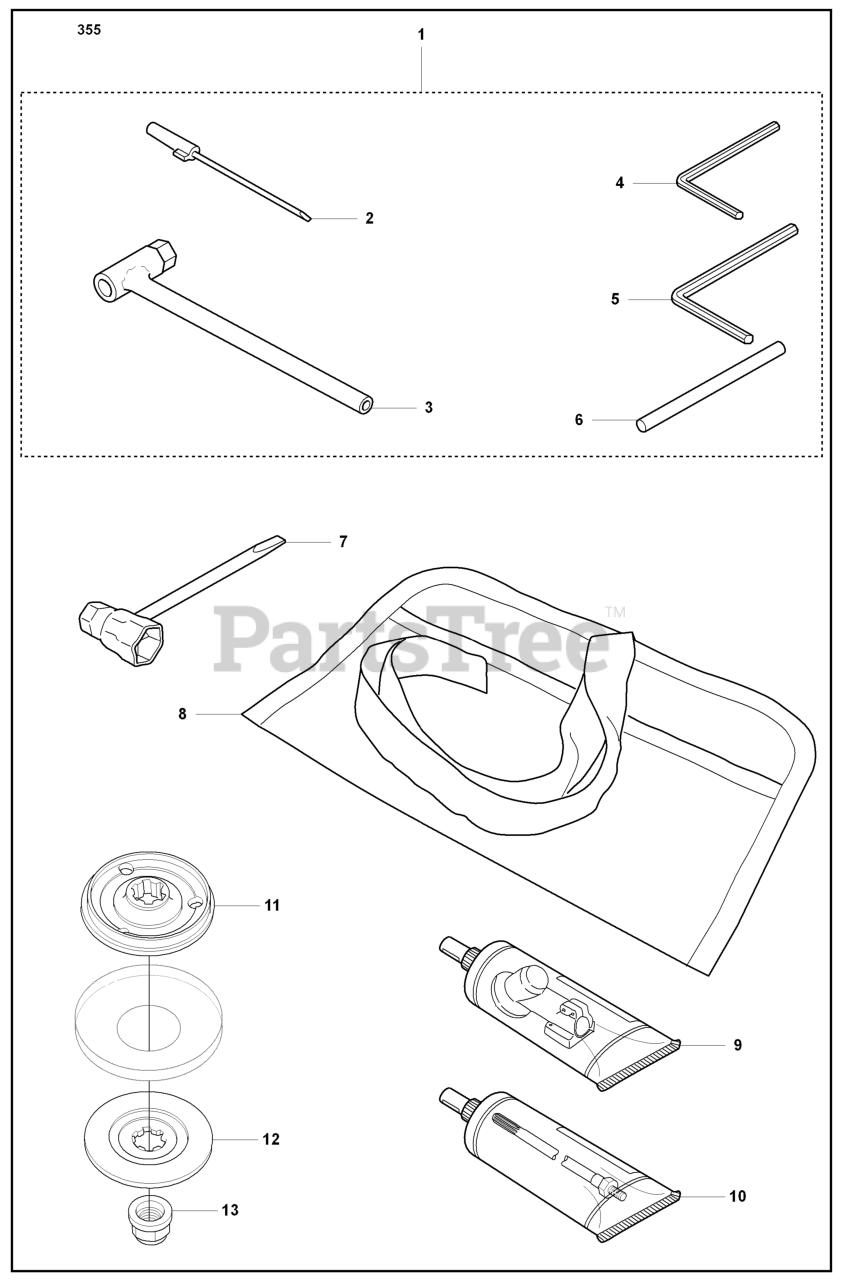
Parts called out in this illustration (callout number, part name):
2	SCREWDRIVER
4	L-KEY WRENCH
5	KEY
6	LOCKING PIN
7	COMBI TOOL
9	BEVEL GEAR GREASE
10	DRIVE SHAFT GREASE (200 G)
11	CARRIER
12	SUPPORT FLANGE
13	BLADE NUT
